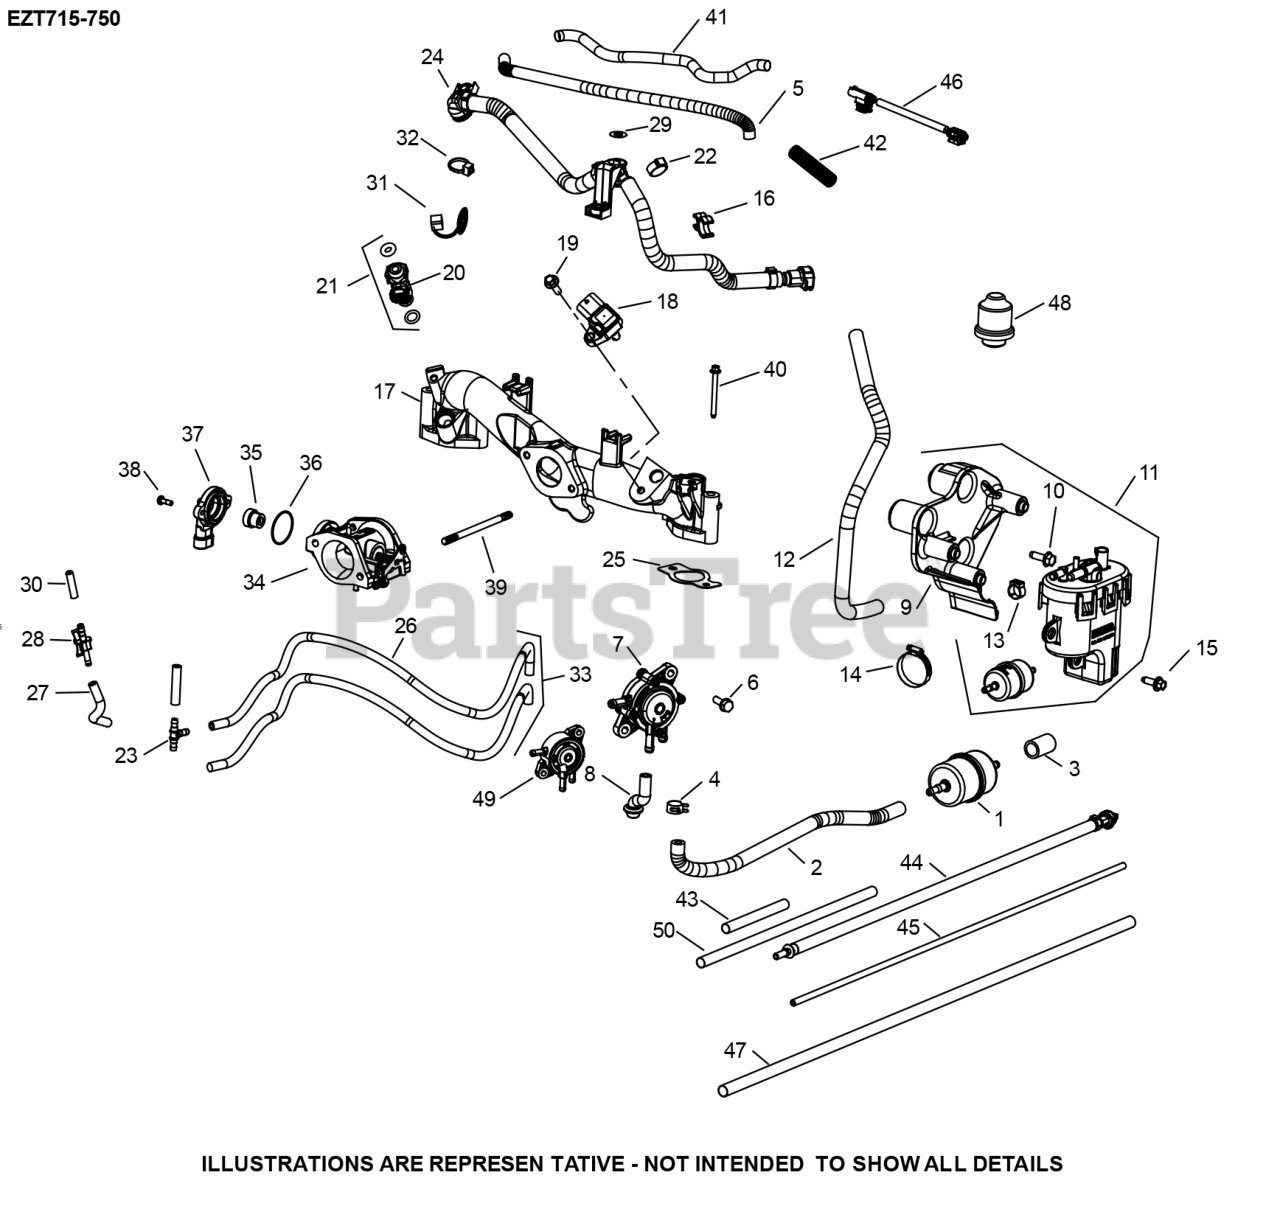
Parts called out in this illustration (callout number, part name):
1	FUEL FILTER
2	FUEL HOSE LO PER
5	SLEEVE-ANTI ABRASION
6	HEX HEAD SCREW
7	FUEL PUMP
8	HOSE-PULSE PUMP
9	FUEL MODULE BAFFLE
10	THREAD FORMING SCREW
11	FUEL PUMP MODULE KIT
11	FUEL PUMP MODULE KIT (EZT740/750)
12	INSULATING SLEEVE
13	CLAMP-OETIKER
14	HOSE CLAMP 1/2
15	HEX FLANGE SCREW
16	RETAINING CLIP
17	MACHINED MANIFOLD EFI
19	HEX SCREW FLANGE
20	FUEL INJECTOR
21	KIT-FUEL INJECTOR O-RING
23	TEE CONNECTOR
24	FUEL HOSE ASSEMBLY
25	INTAKE MANIFOLD GASKET
28	CONECTR-EVAPORATIV
29	RETAINER CLIP
31	CONNECTOR CAP
33	HOSE ASSEMBLY
34	THROTTLE BODY ASSEMBLY W/TPS
35	TPS MAGNET ASSEMBLY
37	THROTTLE POSITION SENSOR
40	HEX FLANGE SCREW M6 W/DOG POINT
